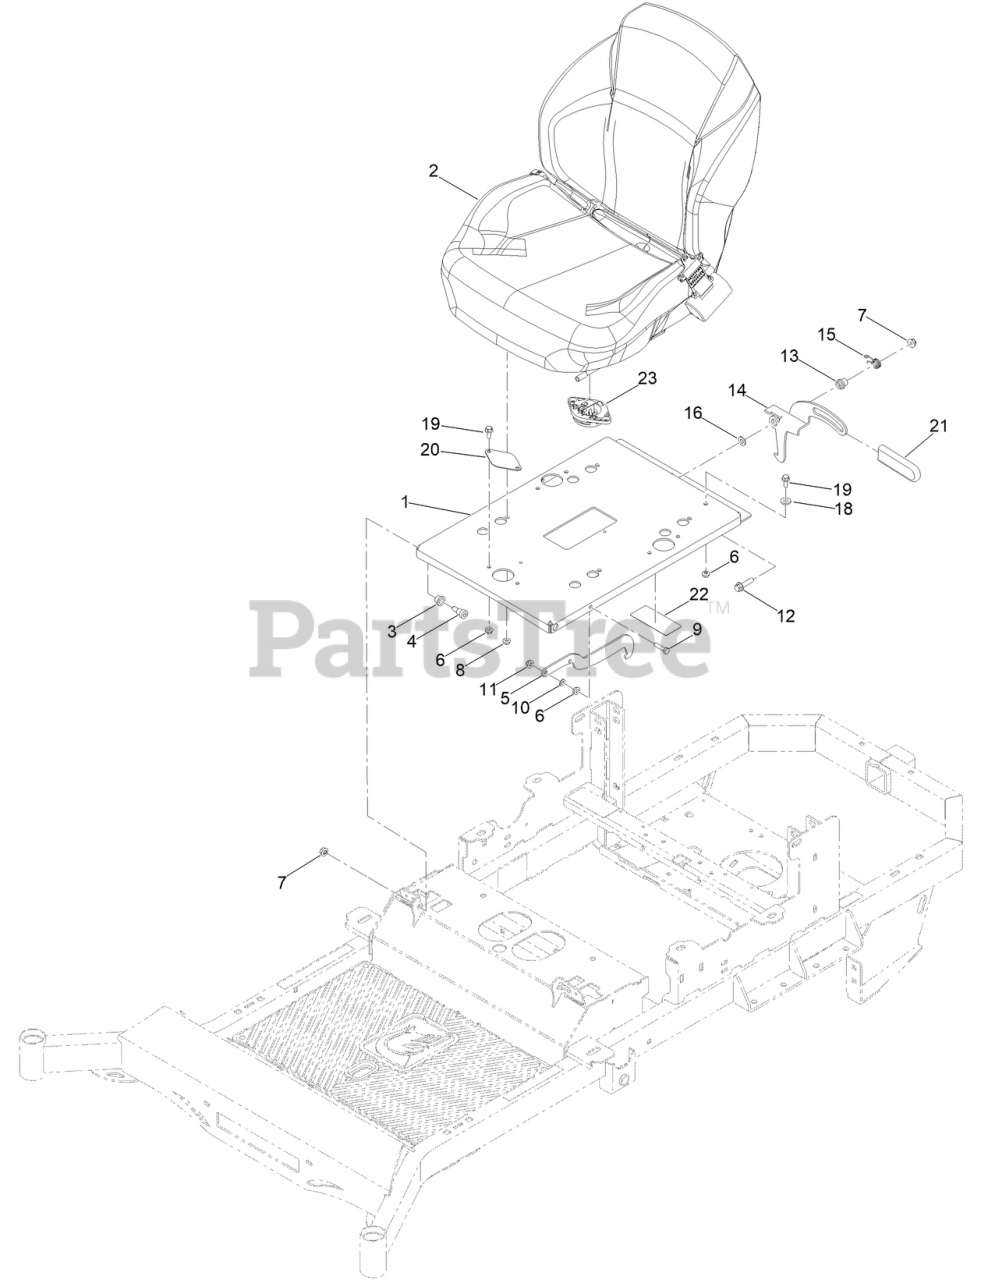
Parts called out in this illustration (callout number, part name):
1	NON 360 SEAT BASE PLATE SAFTY DECAL ASM-
2	RT PRO SEAT
3	1/2IN ID X 5/8IN OD X 1/2IN FLANGE BUSH
4	1/2 X 1/2 SOCKET SHOULDER BOLT ZC YELLOW
5	MWR SEAT LATCH HOOK PAINT
8	5/16-18 NYLON INSERT FLANGE L/NUT ZC
9	SCREW-HH
10	.312IDX.625ODX.062 THK THRUST BRG OI BRZ
11	NUT-HF, NI
12	SCREW-HHF
13	BUSHING-LATCH, SEAT
14	BRACKET-LATCH
15	SPRING-TORSION, LATCH
16	WASHER-FLAT
18	.312 ID X .875OD X .1875 THK F/W NYL
19	SCREW-HHF
20	2020 RT/SRT UNIV FLOAT SEAT CVR PLT
21	STAND UP MWR BRAKE ARM GRIP
22	DECAL-WARNING, BATTERY
23	MWR SEAT SWITCH
